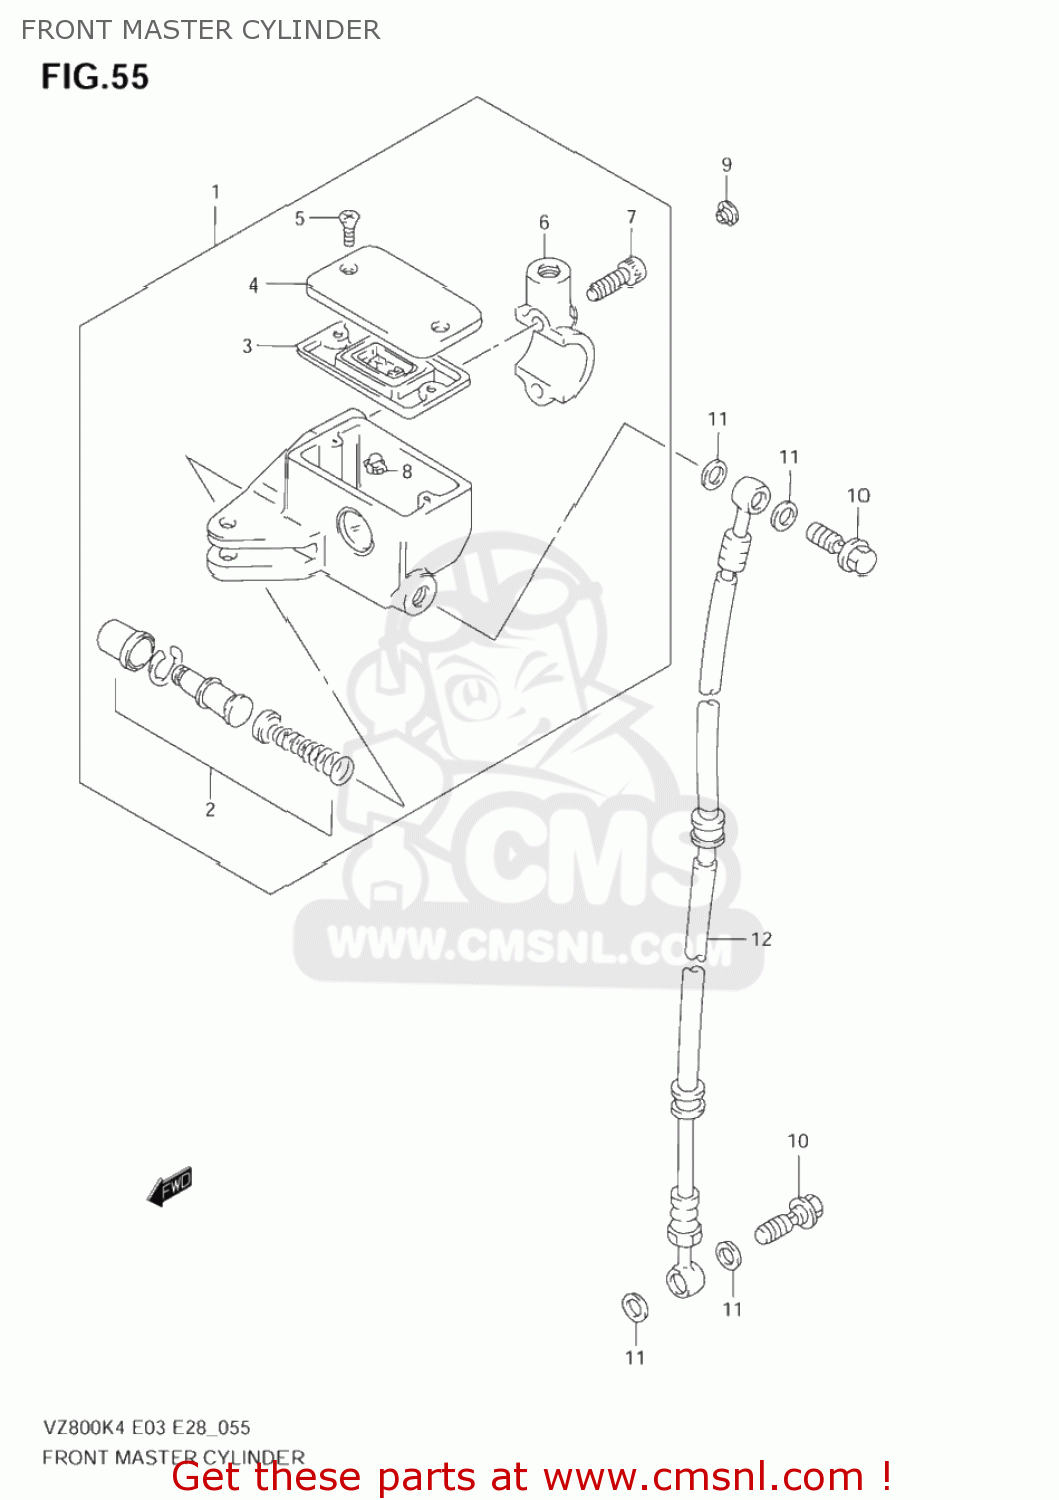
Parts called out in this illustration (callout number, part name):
1	CYLINDER ASSY,FR MASTER
2	PISTON/CUP SET
3	4
4	CAP
5	SCREW
6	HOLDER
7	BOLT
8	PROTECTOR
9	CAP(OD:10)
10	BOLT UNION
11	WASHER(10X15X1.5)
12	HOSE,FR BRAKE
